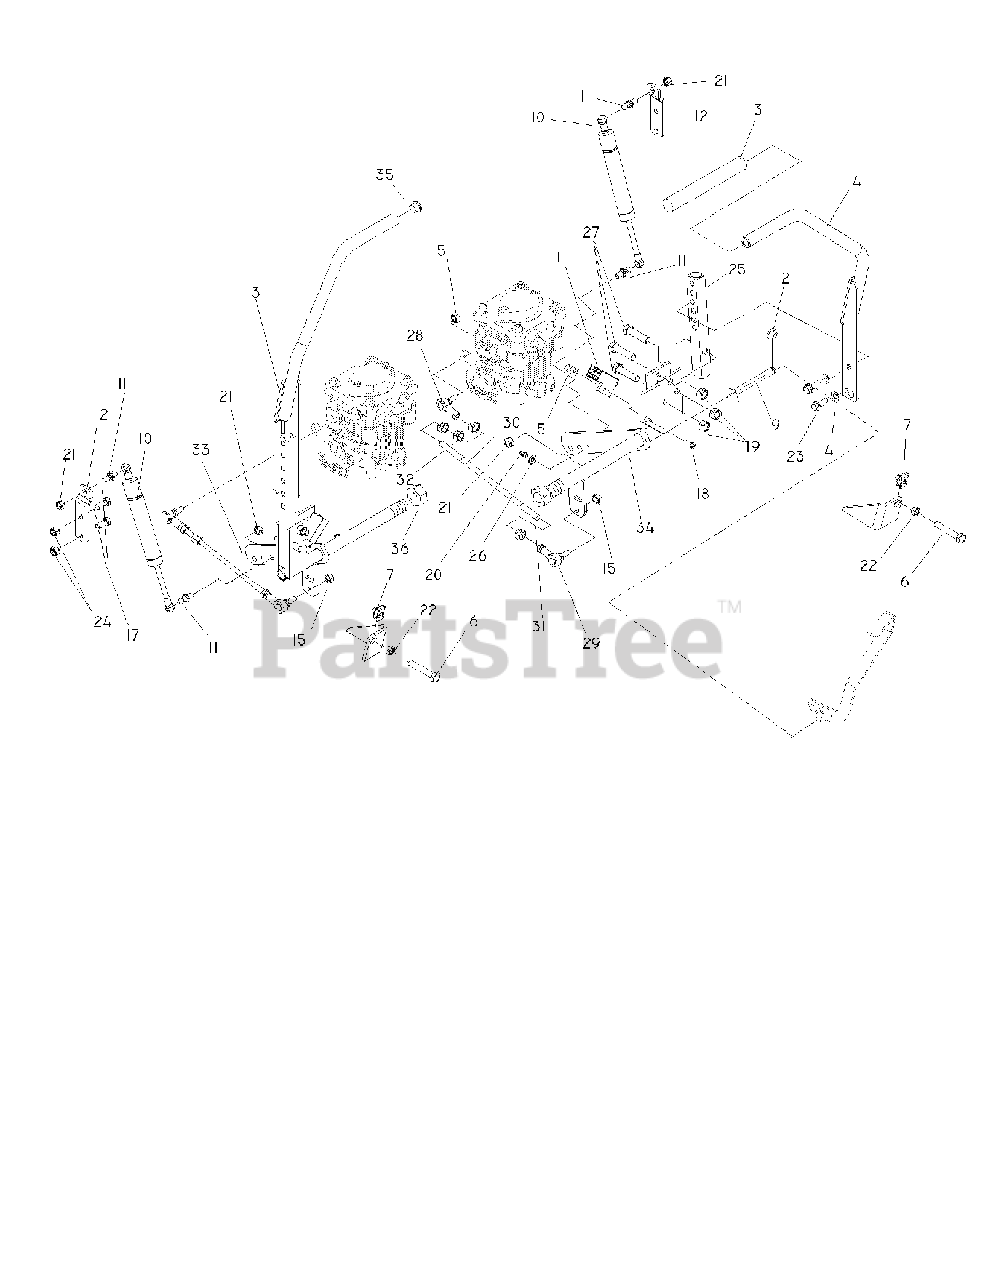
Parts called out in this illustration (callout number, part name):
1	SWITCH, INTERLOCK
2	E-RING 1/2 (2 2)
3	GRIP, FOAM (GROUND) 15
4	WASHER, 3/8 DISC SPRING SPEC
5	TAPPED PLATE
6	HCS 5/16C X 1 1/4
7	U-CLIP 5/16-18 NUT RETAINER
9	CONTROL SHAFT
10	DAMPENER
11	STUD.BALL.10MM
12	DAMPENER ARM
13	LEVER, DRIVE, RT
14	LEVER, DRIVE, LT
15	NUT 5/16F NYLOC
17	HCS 5/16C X 3/4
18	SCREW #10-24 X 5/8
19	NUT 3/8-16 NYLOC
20	ZERK
21	NUT 5/16C CENTERLOCK
22	NUT 5/16C HEX
23	HCS 3/8C X 1
24	NUT 5/16 NYLOC
25	CONTROL ARM
27	HCS 3/8-16 X 1 3/4 GR5
28	SPHERICAL ROD END, RH
29	SPHERICAL ROD END, LH
30	PUMP CONTROL LINK
31	NUT 5/16F LEFTHAND
32	NUT 5/16F
33	CONTROL-DRIVE RT
35	END PLUG 15/16` (BLACK)
36	NUT 3/4 X 16 HEX CTR
